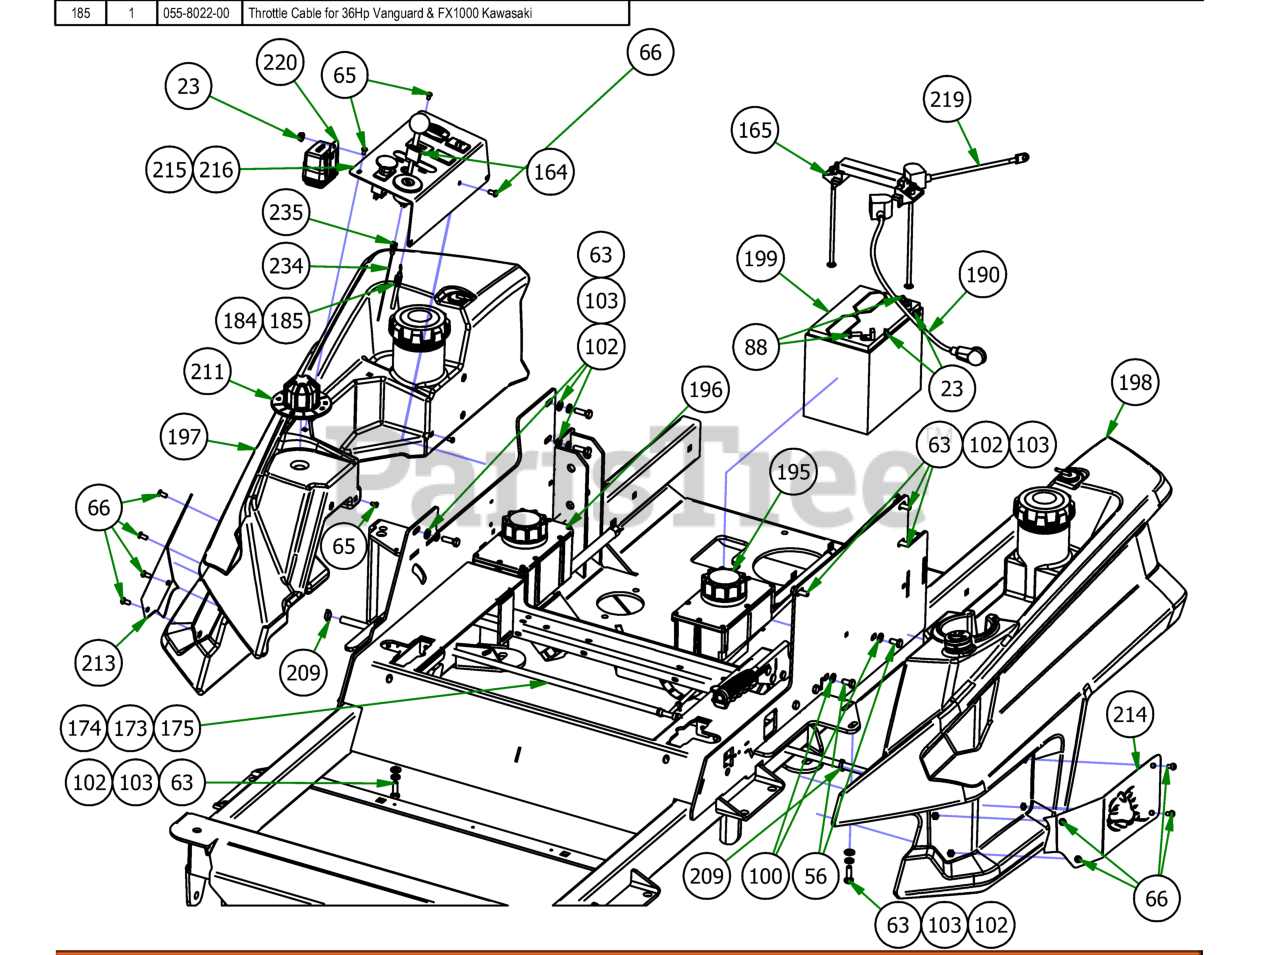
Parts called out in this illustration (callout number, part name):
23	1/4-20 Hex Flange Nuts Zinc w/Serrations
56	5/16-18 x 5/8 Hex Bolt
63	5/16" x 1" Bolt
65	10-32 x 3/8" Button Socket Head Bolt
66	1/4" x 1/2" BS C/S 18-8 SS
88	1/4" x 3/4" Hex Bolt
100	1/4 USS Flat Washer Zinc
102	5/16" Flat Washer
103	5/16" Lock Washer
164	Ignition Key
165	Hold Down Assembly
173	2019 Rebel Rogue Renegade Fuel Line for Vanguard & Yamaha
174	2019 Rebel Rogue Renegade Fuel Line for Kohler
175	2019 Rebel Rogue Renegade Fuel Line for Kawasaki
184	Outlaw Throttle Cable
185	Throttle Cable for 36Hp Vanguard & FX1000 Kawasaki
190	24" Red Battery Cable
195	LH Rogue Hydro Tank Assy
196	RH Rogue Hydro Tank Assy
197	2019 Right Rebel, Rogue, Renagade Fuel Tank (GAS)
198	2019 Left Rebel, Rogue, Renegade Fuel Tank (GAS)
199	SP-35 Battery
206	2019 Veritical Suspension Frame
209	2 EAR CLAMP 12.5mm-15mm
211	2019 Deck Height Dial
213	2019 Outlaw Fuel Tank Insert - Right
214	2019 Outlaw Fuel Tank Insert - Left
215	Rebel/Rogue EFI Control Panel Assy
216	Rebel/Rogue Control Panel Assy
219	Starter Cable
220	2019 Wiring Harness-Rebel/Rogue
234	16 AWG Black Insulated Wire for Tachometer
235	1/4" Female Quick Connect Terminal
